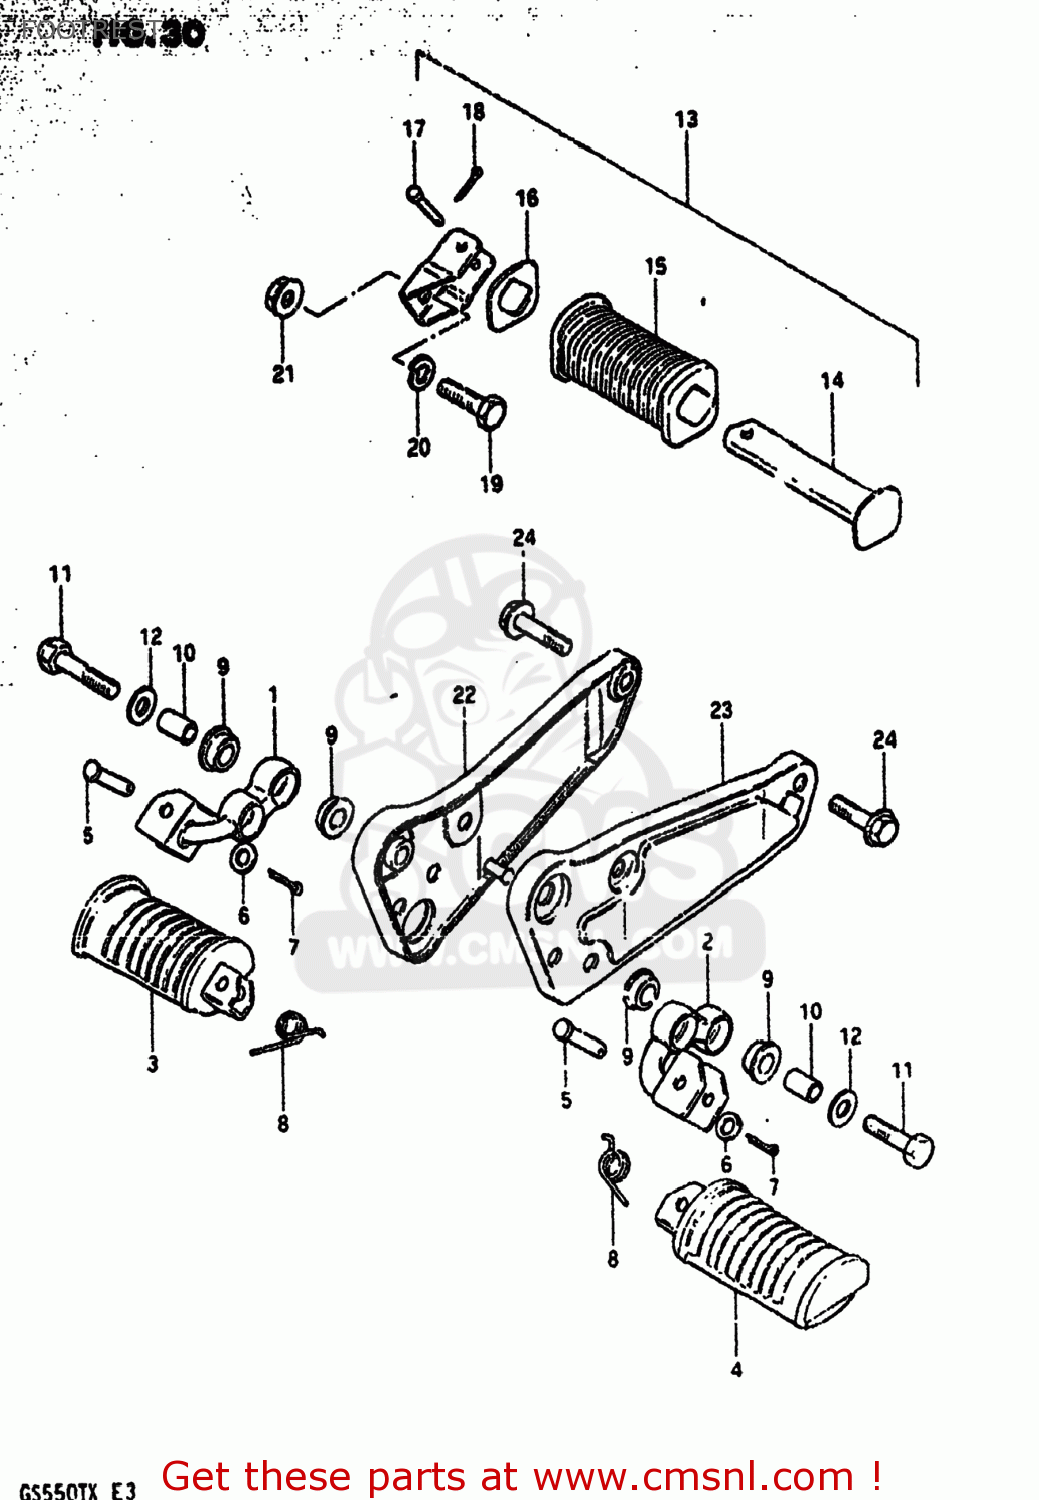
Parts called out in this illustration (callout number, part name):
1	BAR,FRONT FOOTREST
2	FOOTREST,FRONT,LEFT
3	RUBBER,PILLION FOOTREST,R
4	RUBBER,PILLION FOOTREST,L
5	PIN
6	WASHER
7	PIN
8	SPRING
9	BUSH
10	SPACER (10.2X14X20)
11	BOLT
12	WASHER(10.5X28X2.3)
13	FOOTREST ASSY,PILLION,R
14	BAR,REAR FOOTREST,LEFT
15	RUBBER,PILLION FOOTREST
16	WASHER,FOOTREST RUBBER
17	PIN
18	PIN
19	BOLT,M10X1.25X
20	LOCK WASHER
21	NUT
22	BRACKET,MUFFLER,RIGHT
23	BRACKET,MUFFLER,LEFT
24	BOLT
